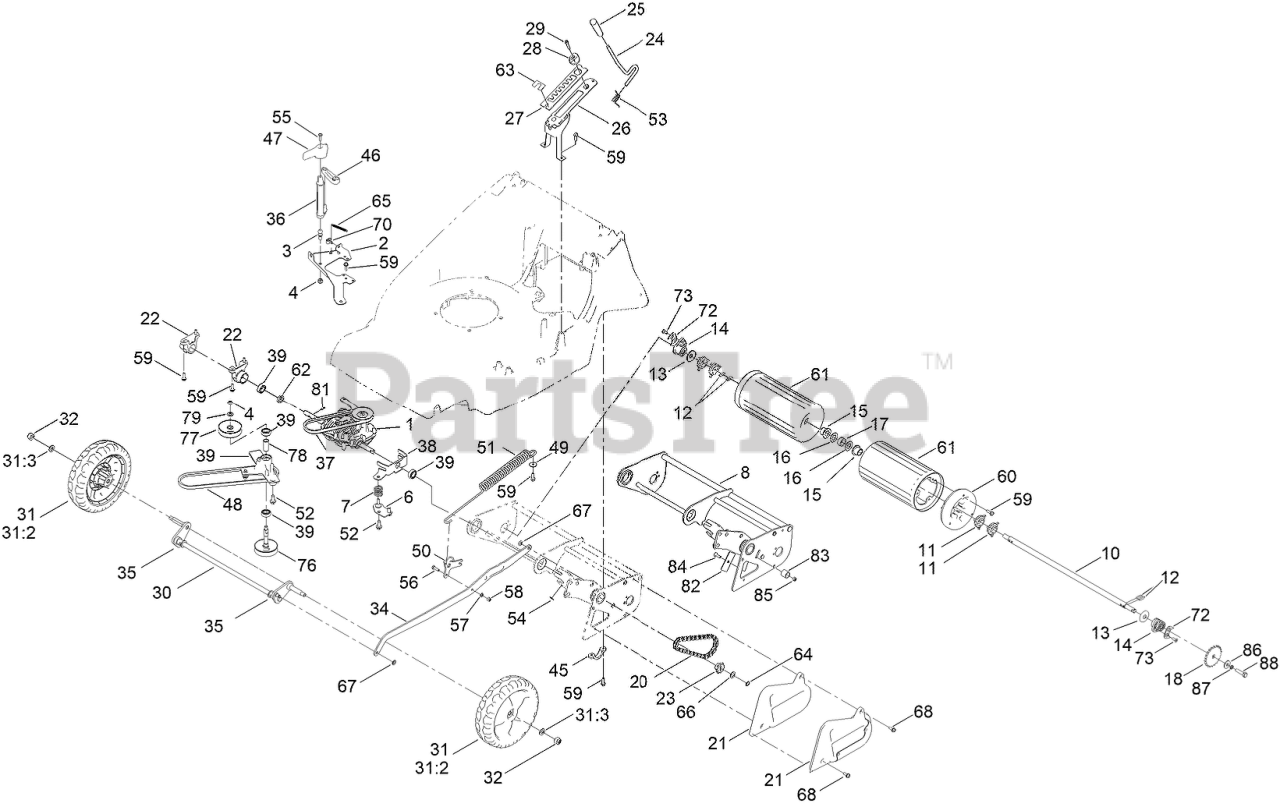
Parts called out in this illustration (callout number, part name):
1	MG510 3-SPEED GEARBOX
2	GEARBOX MOUNTING PLATE
3	STUD-BALL
4	NUT-HEX, NI
6	GEARBOX BRACKET ASSEMBLY
7	SPRING-MOUNTING, GEARBOX
8	REAR AXLE FRAME ASSEMBLY
10	SHAFT-ROLLER, PRO
11	CAM-DRIVE
12	KEY-DRIVE
13	WASHER-THRUST
14	BUSH, REAR ROLLER
15	BUSHING-ROLLER, OILITE
16	WASHER
17	SPACER-ROLLER
18	SPROCKET
21	CHAIN COVER ASM
22	MOUNT-BEARING, FRAME (REAR)
23	SPROCKET, 10T
24	LEVER-HOC
25	KNOB-HOC
26	HOC TOWER ASSEMBLY
27	PLATE-HOC
28	ADJUSTER-HOC
29	SCREW-HSH
30	56 FRONT AXLE ASSEMBLY HD
31:2	BEARING-BALL
31:3	SPACER
32	NUT-HF, NI
34	CONNECTING ROD ASSEMBLY
35	BEARING-AXLE, FRONT
36	ROD-SELECTOR, 3 SPEED
37	V-BELT
38	JACK SHAFT BRACKET
39	BEARING, BALL 12MM
45	AXLE- SUPPORT, REAR
46	ARM-SELECTOR, 3 SPEED
47	KNOB- SELECTOR, 3 SPEED
48	V-BELT
49	WASHER
50	SPRING LOAD LEVER
51	SPRING COUNTER BALANCE
52	SCREW-HWH
53	SPRING-TORSION, HOC
54	GRIP-FIX
55	SCREW
56	SCREW-HH
57	WASHER-PLAIN
58	NUT-NYLOC
59	SCREW-TAPTITE
60	CAP-ROLLER, END
61	ROLLER SHELL ASSEMBLY
62	RETAINING COLLAR, DRIVE SHAFT
63	DECAL-HOC
64	CIRCLIP-EXTERNAL, HD
65	LEVER-SPRING, CLUTCH (RETURN)
66	WASHER-THRUST
67	WASHER-STARLOCK
68	SCREW-TAPTITE
70	CLIP-CONDUIT, TWIN
72	BEARING SUPPORT PLATE
73	SCREW-TAPTITE
76	WELDED JACK SHAFT ASM
77	SPLIT PULLEY UPPER
78	SPACER TUBE, BEARING
79	WASHER-PLAIN
81	PIN, ROLL, 3MM X 16MM
82	BACK PLATE, TENSIONER
83	PULLEY, TENSIONER
84	BOLT-COACH
85	NUT-NYLOC
86	WASHER-PLAIN
87	WASHER-SPRING
88	BOLT-HH
